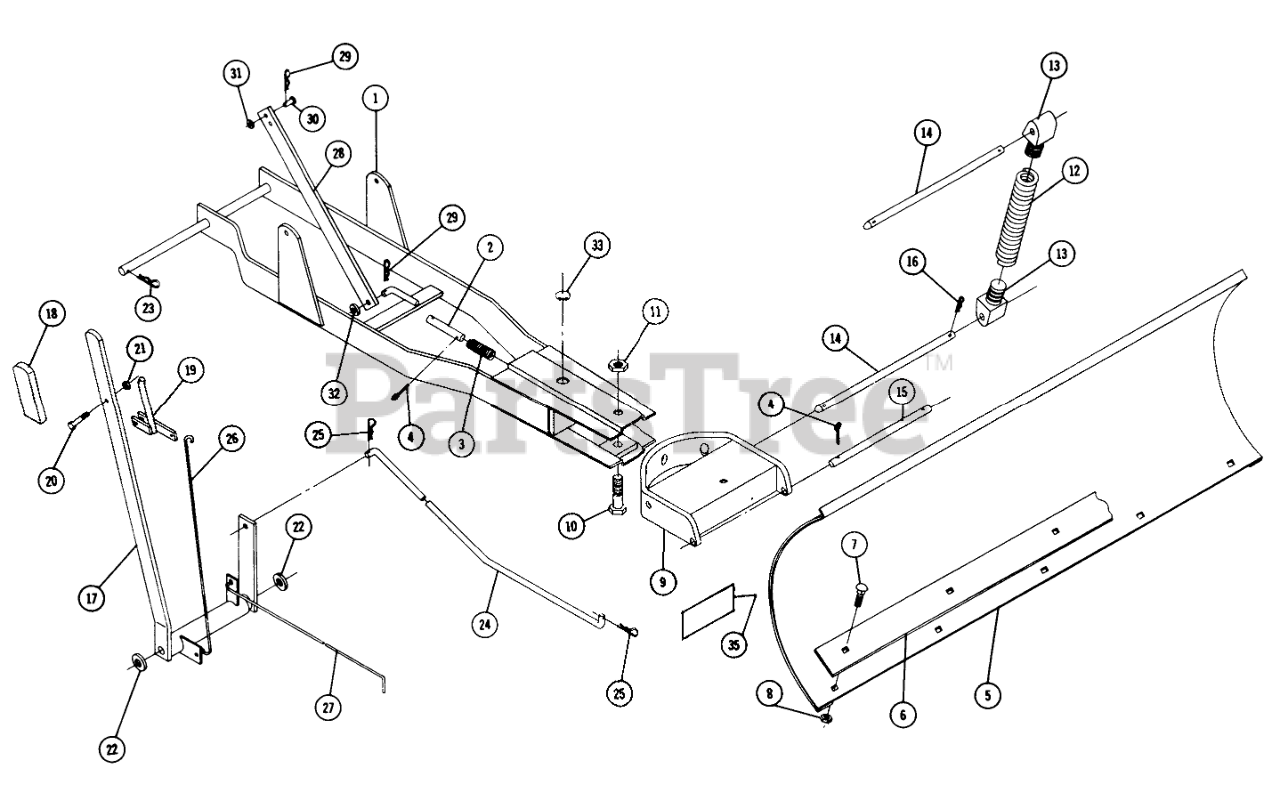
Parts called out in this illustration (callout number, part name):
1	Frame
2	Index Pin
3	SPRING-COMPRESSION
5	Blade
6	Plate
7	Bolt-Carriage
8	NUT
9	Sector and Channel
10	Bolt
11	Nut
12	Spring
13	Lug
14	ROD-PIVOT, BLADE
15	ROD-LOWER
16	Hairpin
17	Index Lever
18	GRIP
19	LEVER ASSY
20	Bolt
21	Nut
22	Washer
23	Hairpin
24	Brake Pedal
25	Hairpin
26	Upper Index Rod
27	LOWER INDEX ROD
28	Lift Bar
29	Hairpin Cotter
31	Washer
32	WASHER
33	PLUG
33	Caution Decal
33	DECAL-WHEEL HORSE
